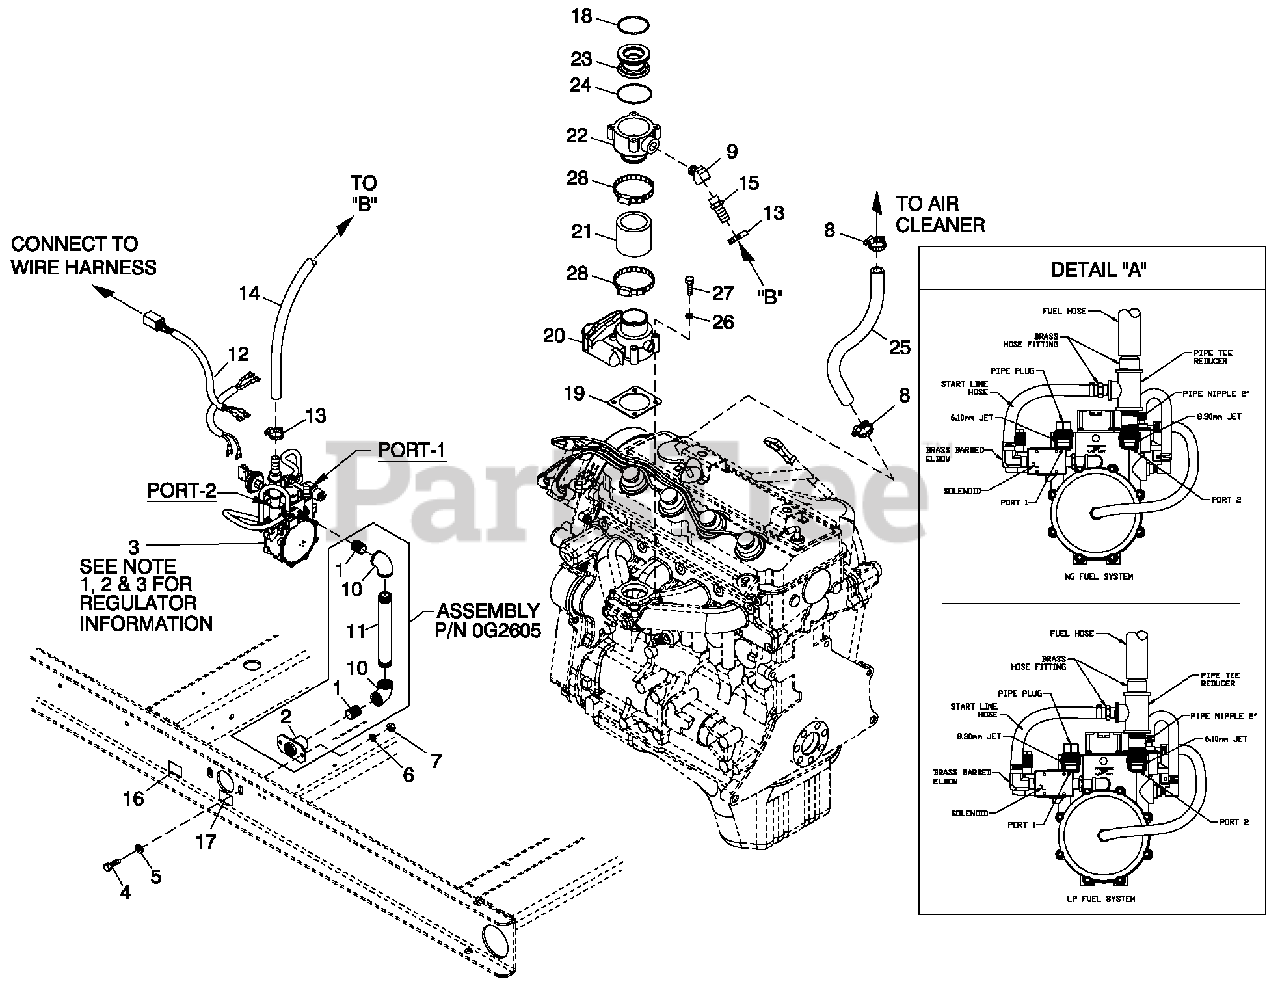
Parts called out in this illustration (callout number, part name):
1	NIPPLE PIPE 3/4 NPT X 2
2	FLANGEIFUELIINLETI
3	REGULATORIASSYI2.4LIEMISSIONSI
4	SCREW HHC M8-1.25X 20 G8.8
5	WASHER FLAT 5/16-M8 ZINC
6	WASHER LOCK M8-5/16
7	NUTIHEXIM8-1.25IG8ICLEARIZINCI
8	CLAMP HOSE #5.5.62-.62
9	STREET EL 45D1/2 NPT BRASS
10	ELBO I90DI3/4INPTI
11	NIPPLE PIPE 3/4 NPT X 7
12	HARNESS CPL FUEL JUMPER
13	CLAMP HOSE #10 .56-1.06
14	HOSE 3/4 ID SAE-30R2 (16" LG)
15	BARBED STR 1/2 NPT X 3/4
16	DECALIINLETIPRESSUREI
17	DECALIFUELIINLETINGI(NATURALIGASIAPPLICATION)
18	O-RING 45.63 ID X 2.62 WIDTH
19	GASKET BOSCH 32
20	ACTUATOR BOSCH 32, GOVERNOR (35KW ONLY)
21	HOSE 1.5 ID X 2 LG 20R4 (35KW ONLY)
22	MIXER ACTUATOR 32MM MACHINED (35KW ONLY)
23	VENTURI THROTTLE 19MM (35KW ONLY)
24	O-RING 47.625 ID X 2.38 WIDTH
25	HOSE 3/8 ID SINGLE BRAID (18" LG)
26	WASHER LOCK M6-1/4
27	SCREW SHC M6-1.0 X 45 G12.9
28	CLAMPIHOSEI#28I1.32-2.25I
